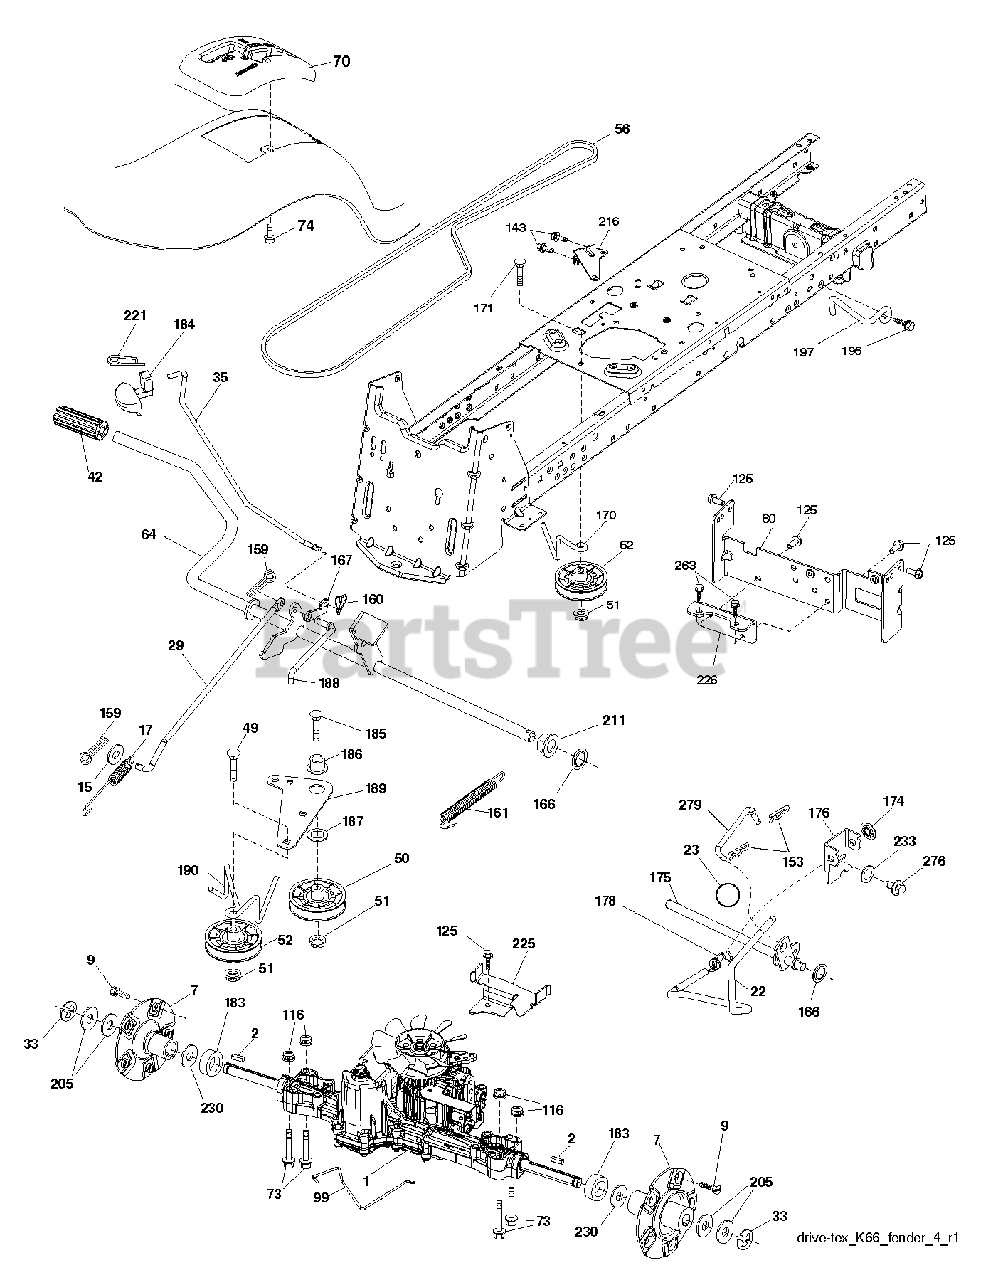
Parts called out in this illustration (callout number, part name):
2	KEY 1/4 X 2.5
7	HUB.ASM.WHEEL.REAR.23"TEX
9	HUB BOLT
17	SPRING.BRAKE.K46
22	ROD.SHIFT.FENDER.STGT.
23	KNOB.DELUXE.(PISTOL.GRIP).BLAC
29	ROD.BRAKE.K66
33	E RING HYT
35	ROD.BRAKE.PARKING.LT.T
49	BOLT
50	IDLER.FLAT.910.OFFSET
51	NUT LOCK FLG 3/8-16 UNC
52	IDLER.V-GROOVE.910.OFFSET
64	SHAFT.ASM.PEDAL.BRAKE.
70	PAD.FOOTREST.RH.STGT.BLACK
73	BOLT HEX 5/16-18 GR 5
74	SCREW.HI-LO.CONSOLE
80	STRAP.TORQUE.K66
99	ROD.SPRING.BYPASS.K66.GT.Z
116	NUT LOCK HEX FLANGE 5/16-18
125	SCREW
143	SCREW LT
159	COTTER PIN
160	RETAINER CLIP
161	SPRING, RETURN LT
166	NUT.PUSH.625
167	LATCH.BRAKE.SPRING
170	KEEPER.V-IDLER.CENTER.
171	BOLT
174	NUT.PUSH.500.2006
175	SHAFT.ASM.SHFT.T2.TLT
176	ARM.CLEVIS.ROD.SHIFT
178	SPRING.SHIFT.GT2006
183	SPACER.AXLE.HG.TEX
184	HANDLE.PARKG.BRK.HUSQ/PRED.667
186	SPACER.RETAINER
187	WASHER 12/32X2X10GA
188	LINK.CLUTCH.GROUND.DRIVE
189	BELLCRANK.GROUND.DRIVE.TEX.
190	KEEPER.BELLCRANK.DRIVE
196	SCREW 3/8-16X1
197	BRKT.ANIT-ROTATION.CLUTCH
211	BUSHING.SHAFT.BRAKE.HAND
216	BRACKET.PULLEY.IDLER.W/TEX
221	RETAINER.SPRING.CLIP.H
225	KEEPER.BELT.TRANSAXLE.K66
226	BRACKET.MOUNT.TORQUE.K66.TG
230	WASHER T
233	WASHER SERRATED
263	SCREW, 3/8-16X3/4
276	BOLT FIN HEX 7/16-14 X 1
279	1INK.ASM.SHIFT.FENDER.K66
